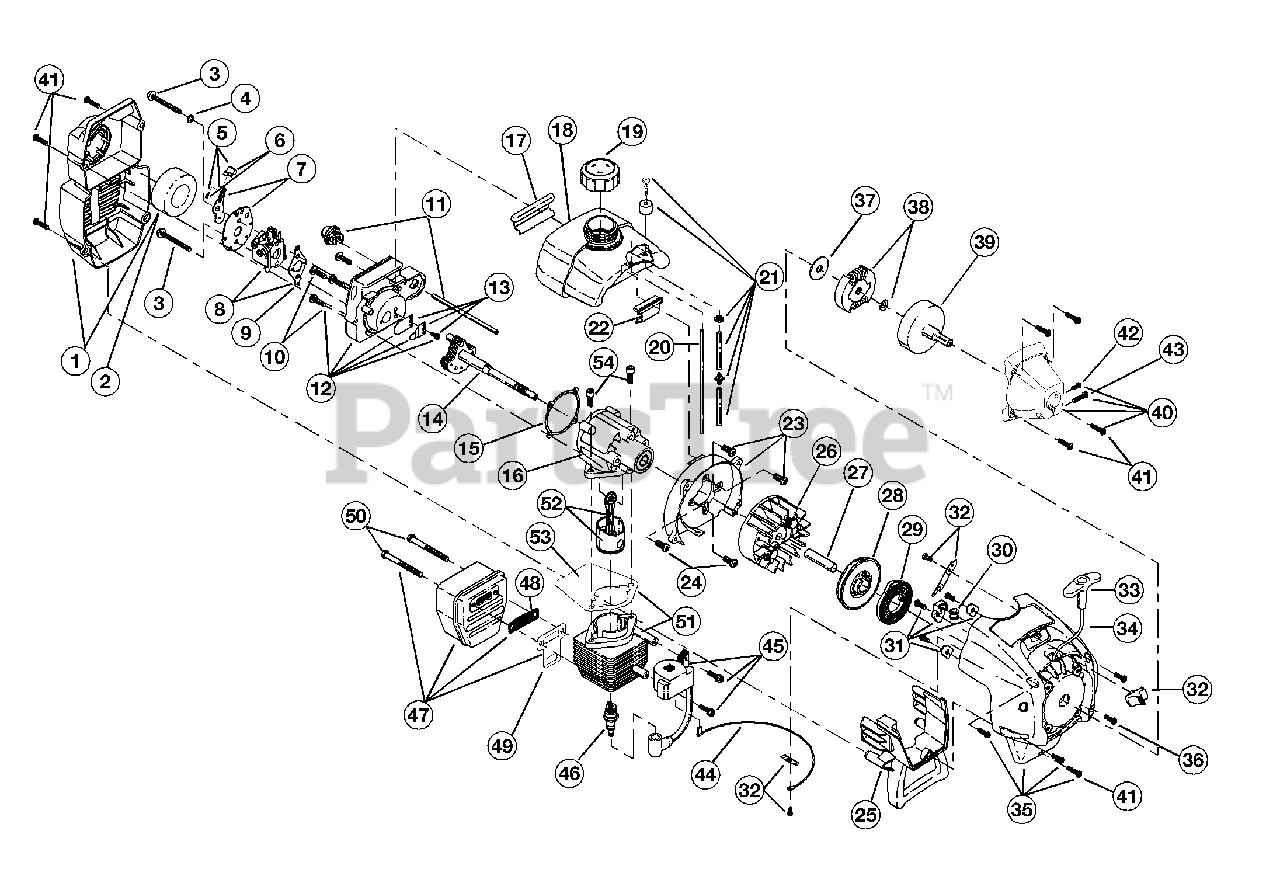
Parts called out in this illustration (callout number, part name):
1	Air Cleaner/Muffler Cover Assembly
2	Air Cleaner Filter
3	Carburetor Mounting Screw Assembly
4	Wavey Washer
5	Choke Lever Assembly
6	Choke Knob and Screw
7	Choke Lever and Plate
8	Carburetor Assembly W/Limiter Caps
9	Carburetor Gasket
10	Carb Mount Screw
11	Primer and Hose Assembly
12	Carb Mount Assembly
13	Reed Assembly
14	Power Shaft Assembly
15	Carburetor Mount Gasket
16	Crank Case Service Assembly
17	Rear Mounting Pad
18	Fuel Tank Assembly
19	Fuel Cap Assembly
20	Fuel Return Line
21	Fuel Line Assembly
22	Front Mounting Pad
23	Shroud Assembly
24	Shroud Screw
25	Shroud Extension and Stand
26	Flywheel Assembly
28	Recoil Pulley Assembly
29	Recoil Spring
30	Rope Guide
31	Pulley Retainer Assembly
32	Switch Assembly
33	Pull Handle
35	Starter Housing Assembly
36	Housing Screw
37	Clutch Washer
38	Clutch Rotor Assembly
39	Clutch Drum Assembly
40	Clutch Cover Assembly
41	Cover Screw
42	Anti-Rotation Screw
43	Clamping Screw
44	Wire Lead
45	Module Assembly
46	Spark Plug
47	Muffler Assembly
48	Spark Arrestor Screen
49	Exhaust Gasket
50	Muffler Mounting Bolt Assembly
51	Cylinder Assembly
52	Piston and Rod Assembly
53	Cylinder Gasket
54	Cylinder Bolt
